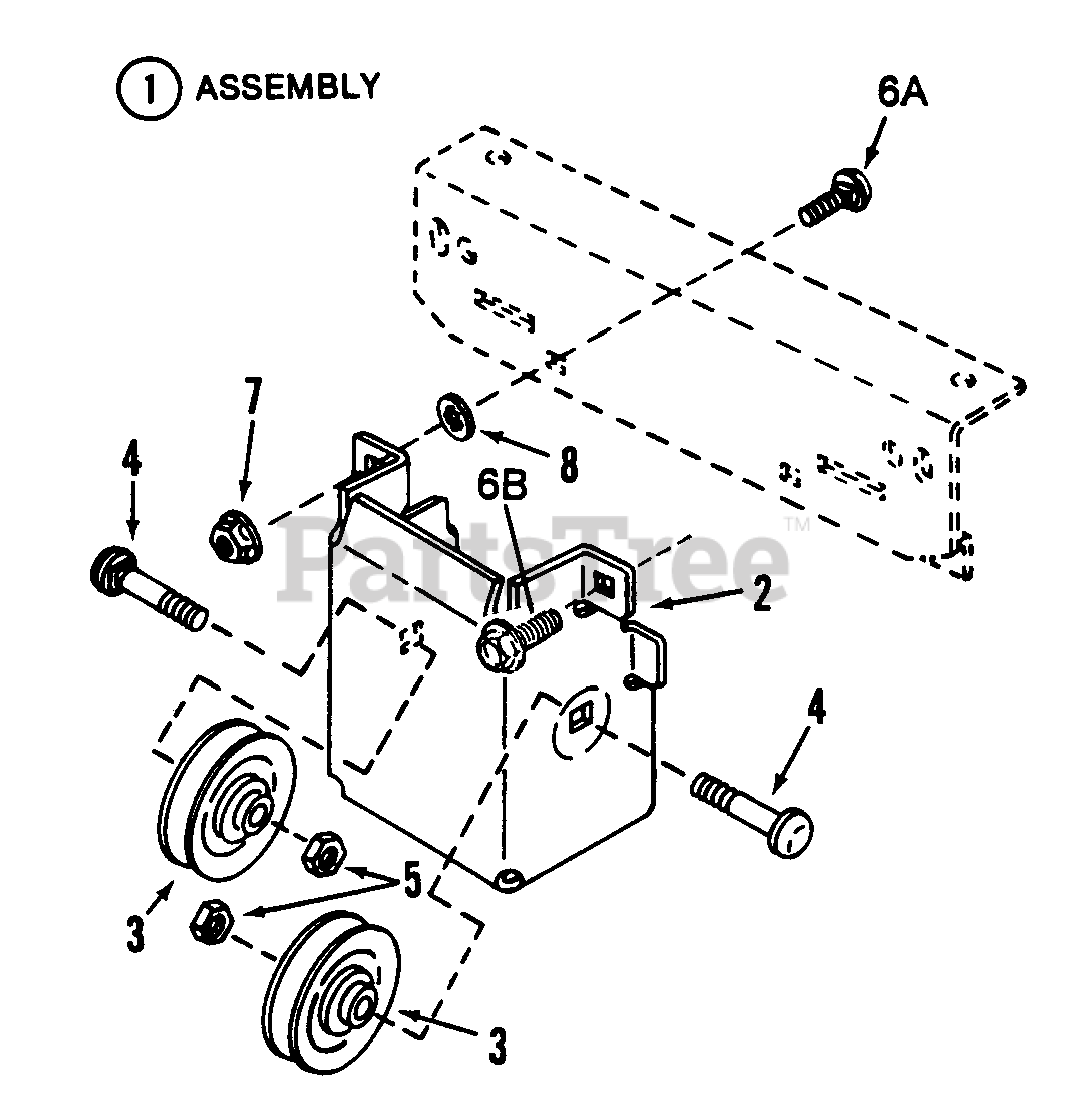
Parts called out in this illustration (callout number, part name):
1	ASSEMBLY, Mule Drive
2	BRACKET, Mule Drive
3	PULLEY, Belt Idler
4	BOLT, 3/8-16 x 1-1/2" Short Square Neck Carriage, Grade 5
5	NUT, 3/8-16 Hex Top Lock
6A	BOLT, 3/8-16 x 3/4" Square Neck Carriage, Grade 2
6B	BOLT, 3/8-16 x 3/4" Hex Flange Lock
7	NUT, 3/8-16 Hex Flange Lock
8	RETAINER, 3/8 Bolt
